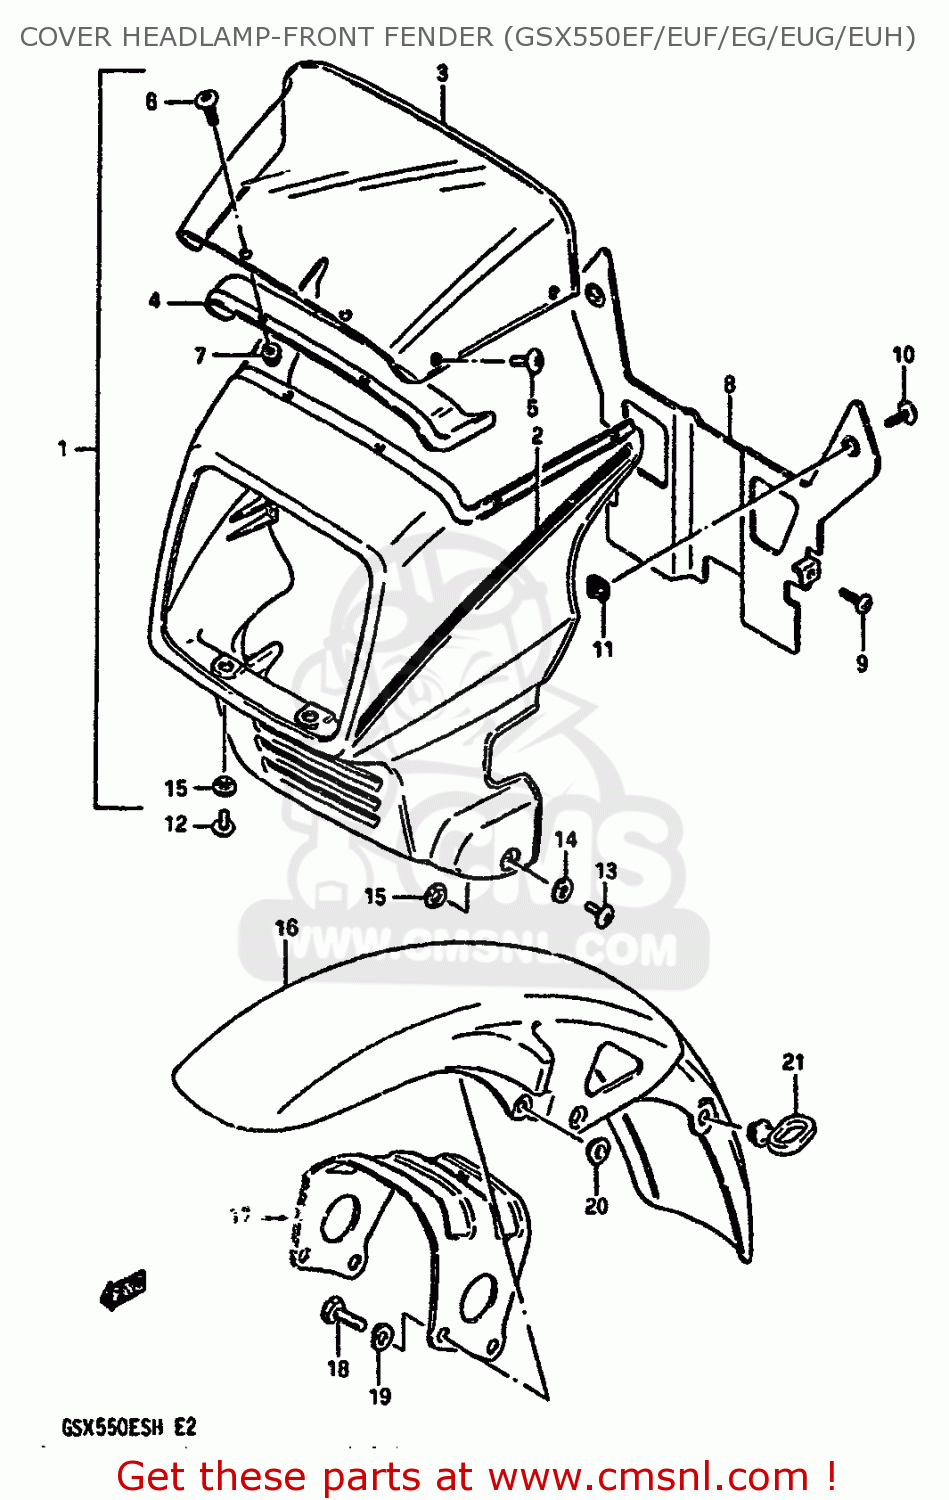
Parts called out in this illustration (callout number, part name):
1	COVER ASSY,HEADLAMP
2	TAPE SET,HEADLAMP
3	WINDOW,COVER HEADLAMP
4	COVER,HEADLAMP,UPPER
5	SCREW(5X12)
6	SCREW
7	NUT
8	PLATE,HEADLAMP COVER
9	SCREW
10	SCREW
11	NUT
12	SCREW 6X12
13	SCREW 6X12
14	WASHER (6.5X18X1.6)
15	WASHER
16	FENDER,FRONT
17	BRACE,FRONT FENDER
18	BOLT,8X16
19	LOCK WASHER
20	WASHER
21	GUIDE,CABLE
